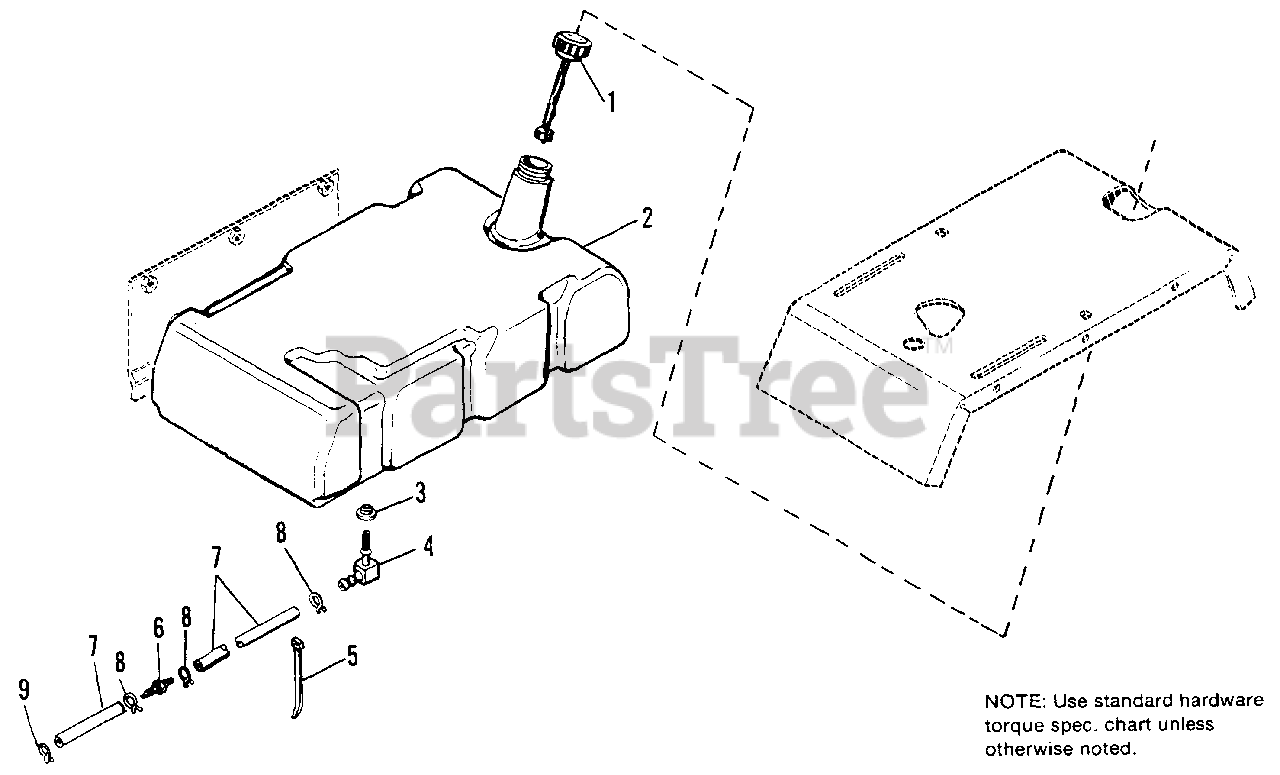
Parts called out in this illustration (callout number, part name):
1	CAP, Gas, w/Gauge
2	FUEL TANK & FITTINGS (Incl. Ref. Nos. 3 & 4)
5	TIE, Self-Locking
6	MENDER, Hose
7	HOSE, Fuel, 1/4 I.D. x 50-1/2 LG.
8	CLAMP, Hose
9	CLAMP, Hose
